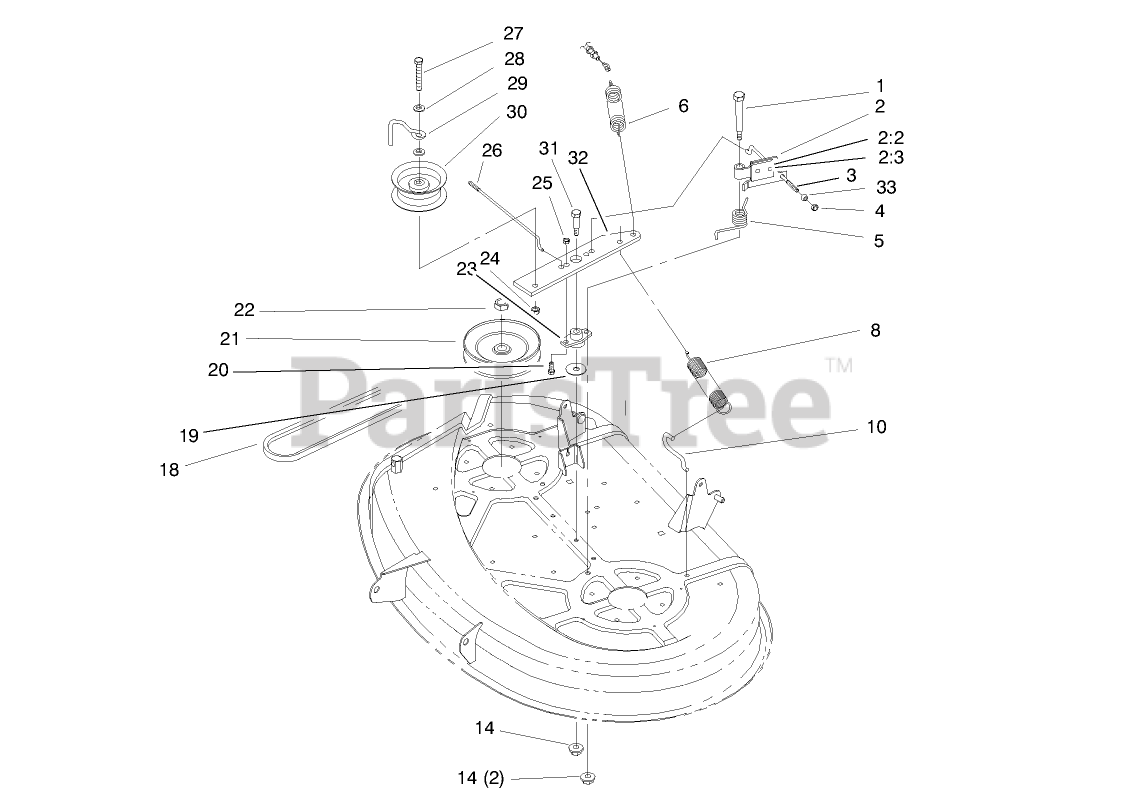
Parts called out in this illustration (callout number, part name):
1	BOLT-SHOULDER
2	BRAKE ASM
2:2	PAD-BRAKE
2:3	RIVET-BLIND
3	ROD-BRAKE, DECK LH
4	NUT-LOCK, NI
5	SPRING-TORSION
6	SPRING-DECK, ENGAGEMENT
8	SPRING-EXTENSION
10	HOOK-RETURN, SPRING
14	NUT-LOCK, NI
18	V-BELT
19	WASHER-FLAT
20	SCREW-HH
21	PULLEY
22	NUT-HEX
23	BUSHING-ARM, IDLER
24	NUT-LOCK, NI
25	NUT-LOCK, NI
26	ROD-BRAKE, DECK RH
27	SCREW-HH
28	WASHER-FLAT
31	SCREW-SHOULDER, HH
32	ARM-IDLER
33	BALL-SWIVEL, STOP
